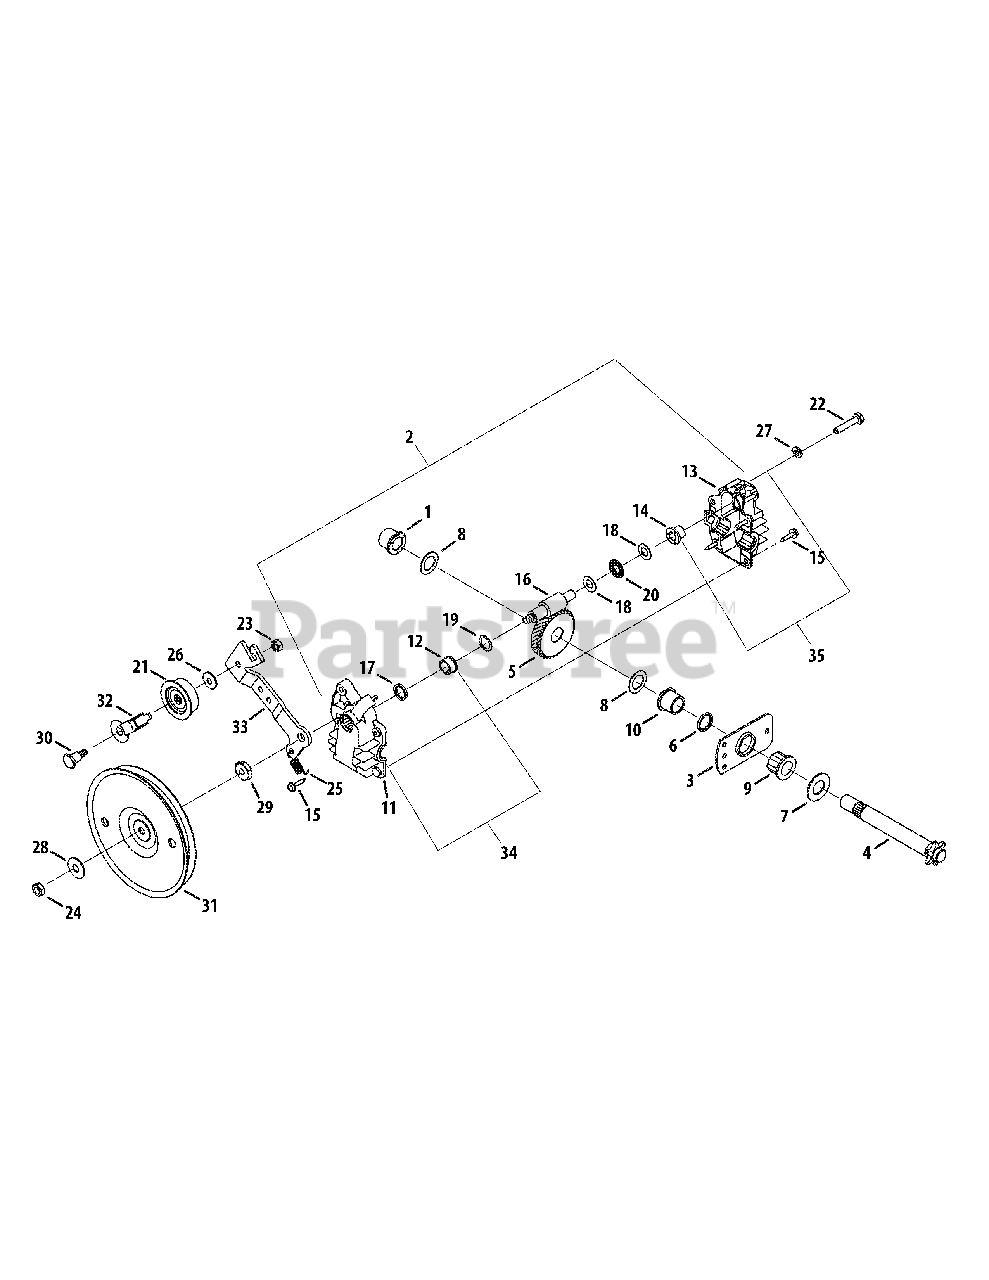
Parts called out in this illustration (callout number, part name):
1	Flange Bearing.566 ID
2	Shredder Transmission Assembly
4	Output Shaft 6T Sprocket
5	Helical 34T Gear
7	Flat Washer, .64 ID x 1.24 OD
8	Flat Washer, 5/8 x 1.0
9	Hex Flange Bearing, .631 ID
10	Flange Bearing, .629 ID
11	Lower Housing
12	Flange Bearing, .503 ID
13	Upper Housing
14	Flange Bearing, .378 ID
15	Hex Washer Screw, #10-16 x.75
16	Pinion Shaft 10T
17	Oil Seal
18	Thrust Washer, .382 ID x.684 OD
19	Flat Washer, .504 ID x.70 OD
20	Thrust Bearing, .375 ID x.812 OD
21	Idler Pulley Assembly W/ Bearing
21	Idler Pulley Only
21	Needle Bearing Only
22	Hex Cap Screw, 1/4-20 x 1.25
23	Hex Nut, 1/4-28
24	Hex Jam Nut, 5/16-24 LH Thd
25	Extension Spring, 1.12 Lg
26	Bell Washer, .265 ID x.75 OD
27	Lock Washer, 1/4
28	Bell Washer, .325 ID x.930 OD
29	Shoulder Spacer, .375 ID x.165 OD
30	Shoulder Bolt, 1/4-28 x.375
31	Flat Pulley 5.06 Dia
32	Belt Keeper
33	Idler Bracket
34	Lower Housing Assembly
35	Upper Housing Assembly
